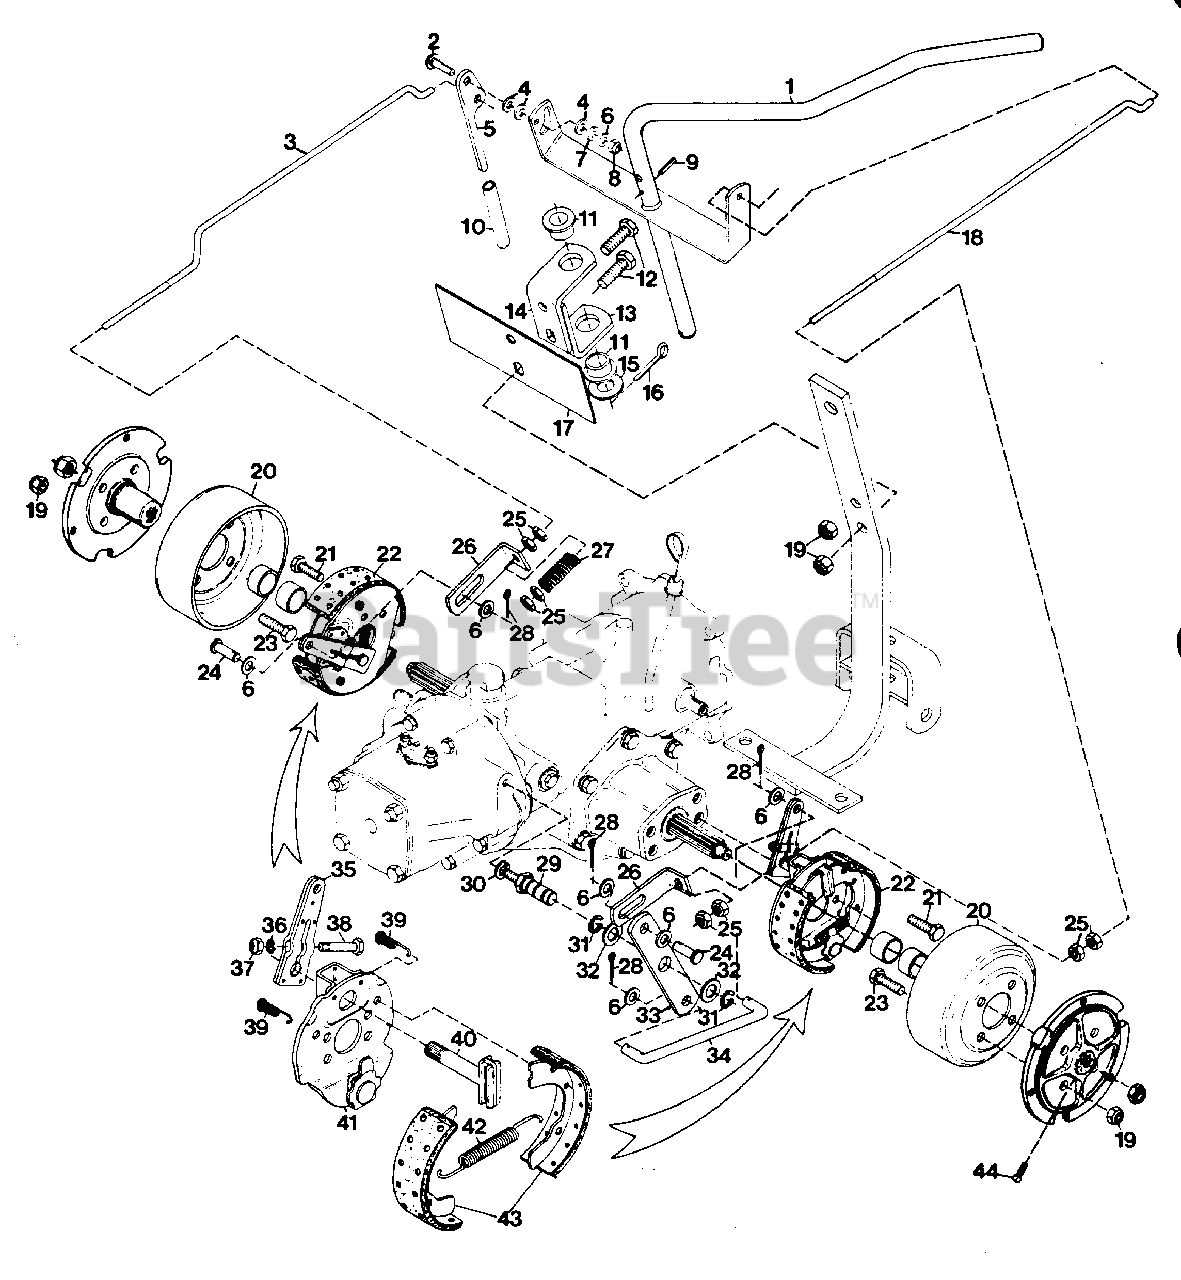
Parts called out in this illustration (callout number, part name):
1	WELDMENT, BRAKE HANDLEBAR
2	BOLT, 3/8-16X1.50 RD HD SQ NK
3	ROD, BRAKE
4	WASHER, NYLON .375X.75X.060
5	HANDLE, PARKING BRAKE
6	WASHER, FLAT .406X.812X.065
7	WASHER, RUBBER .375X.75X.125
8	NUT, LOCK 3/8-16
9	PIN, SPRING .31X2.00
10	GRIP, BRAKE HANDLE
11	BEARING, 1.077X1.38X.75 NYLON
12	BOLT, HEX 1/2-13X2.00
13	BRACKET, BRAKE HANDLE
14	BRACKET, BRAKE HANDLE
15	WASHER, FLAT 1.120X1.50X.092
16	PIN, COTTER .188X1.500
17	PLATE, INSTRUCTION
18	ROD, BRAKE L.H.
19	NUT, LOCK 1/2-13
20	DRUM, 7X1.75
21	BOLT, HEX 3/8-16X.875
22	BRAKE, 7X1.75 MECHANICAL
23	BOLT, HEX 1/2-13X1.375
24	PIN, CLEVIS .375X.750
25	NUT, JAM 3/8-16
26	BRACKET, ADJUSTMENT
27	SPRING, COMPRESSION
28	PIN, COTTER .09X.75
29	STUD, PIVOT
30	WASHER, LOCK 1/2 REG.
31	E-RING, .625 SHAFT
32	WASHER, FLAT .656X1.312X.095
33	PLATE, PIVOT
34	ROD, BRAKE LINK
35	ARM, CAM LEVER
36	WASHER, LOCK 5/16 REG.
37	NUT, HEX 5/16-24
38	BOLT, HEX 5/16-24X1.75
39	SPRING, SHOE RETAINING
40	CAM, BRAKE
41	PLATE, BACK
42	SPRING, SHOE RETURN
43	KIT, BRAKE SHOE
44	SCREW, SET 7/16-14X.75 CPSH
NS	CLAMP, MUFFLER
